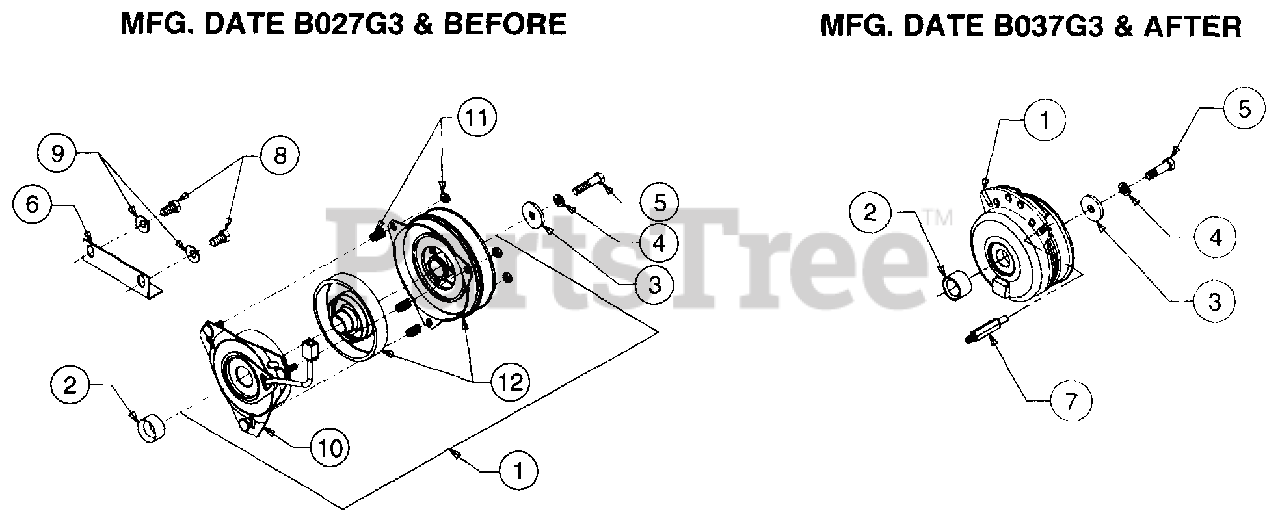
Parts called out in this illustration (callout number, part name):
1	Clutch Assy, PTO
2	Spacer
3	Washer, Flat, .45 x 1.5 x .172
4	Washer, Lock, 3/8
5	Screw, Hex Cap, 3/8-24 x 1.75 GR5
8	Screw, Hex Cap
9	Washer, Bell, .45 x 1.0 x .062
10	Field Assy
11	Clutch Hardware
12	Kit, Armature and Rotor
